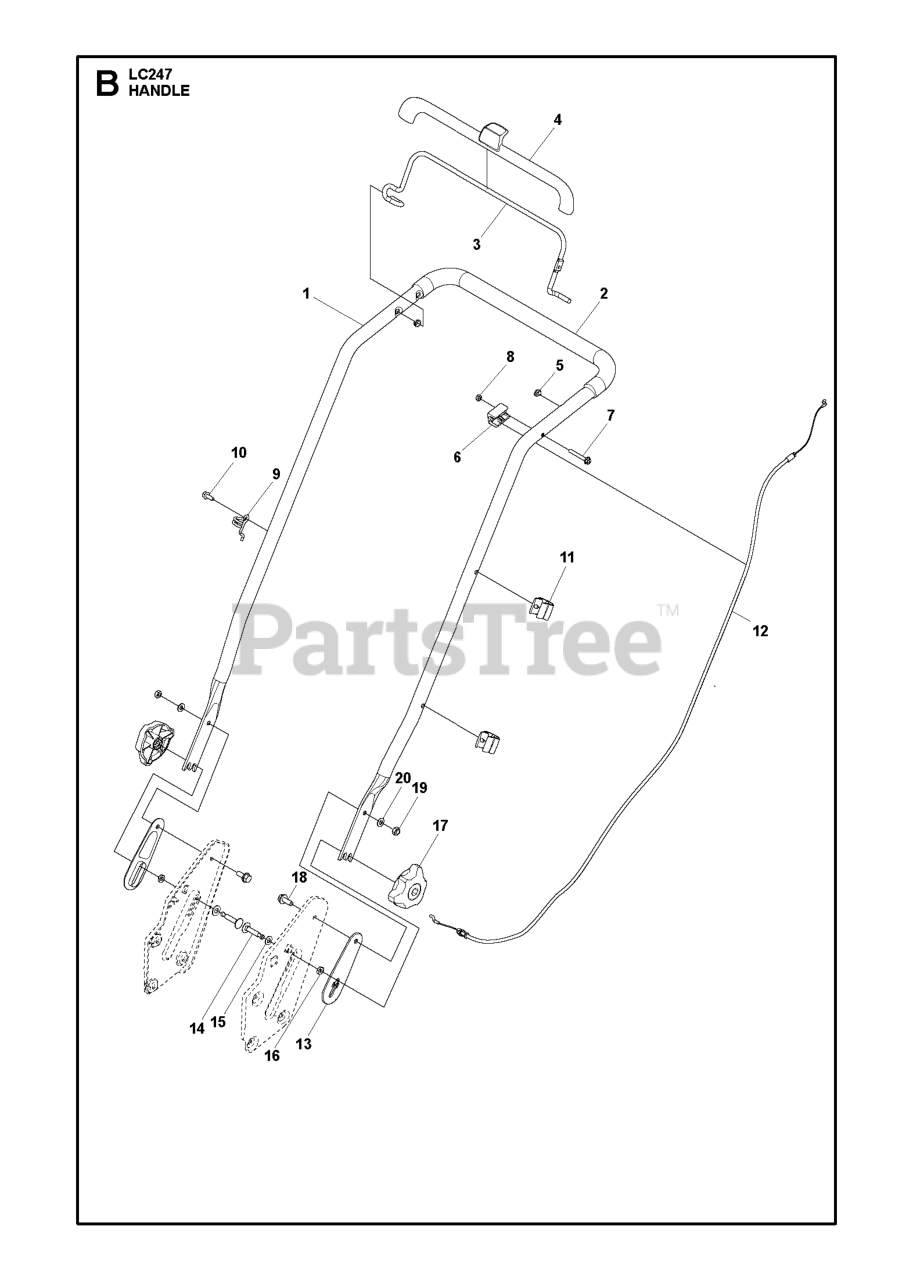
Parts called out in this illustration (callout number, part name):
8	NUT FLANGE - M6
10	SCREW
16	NUT ML6M M8
19	LOCKNUT M8
